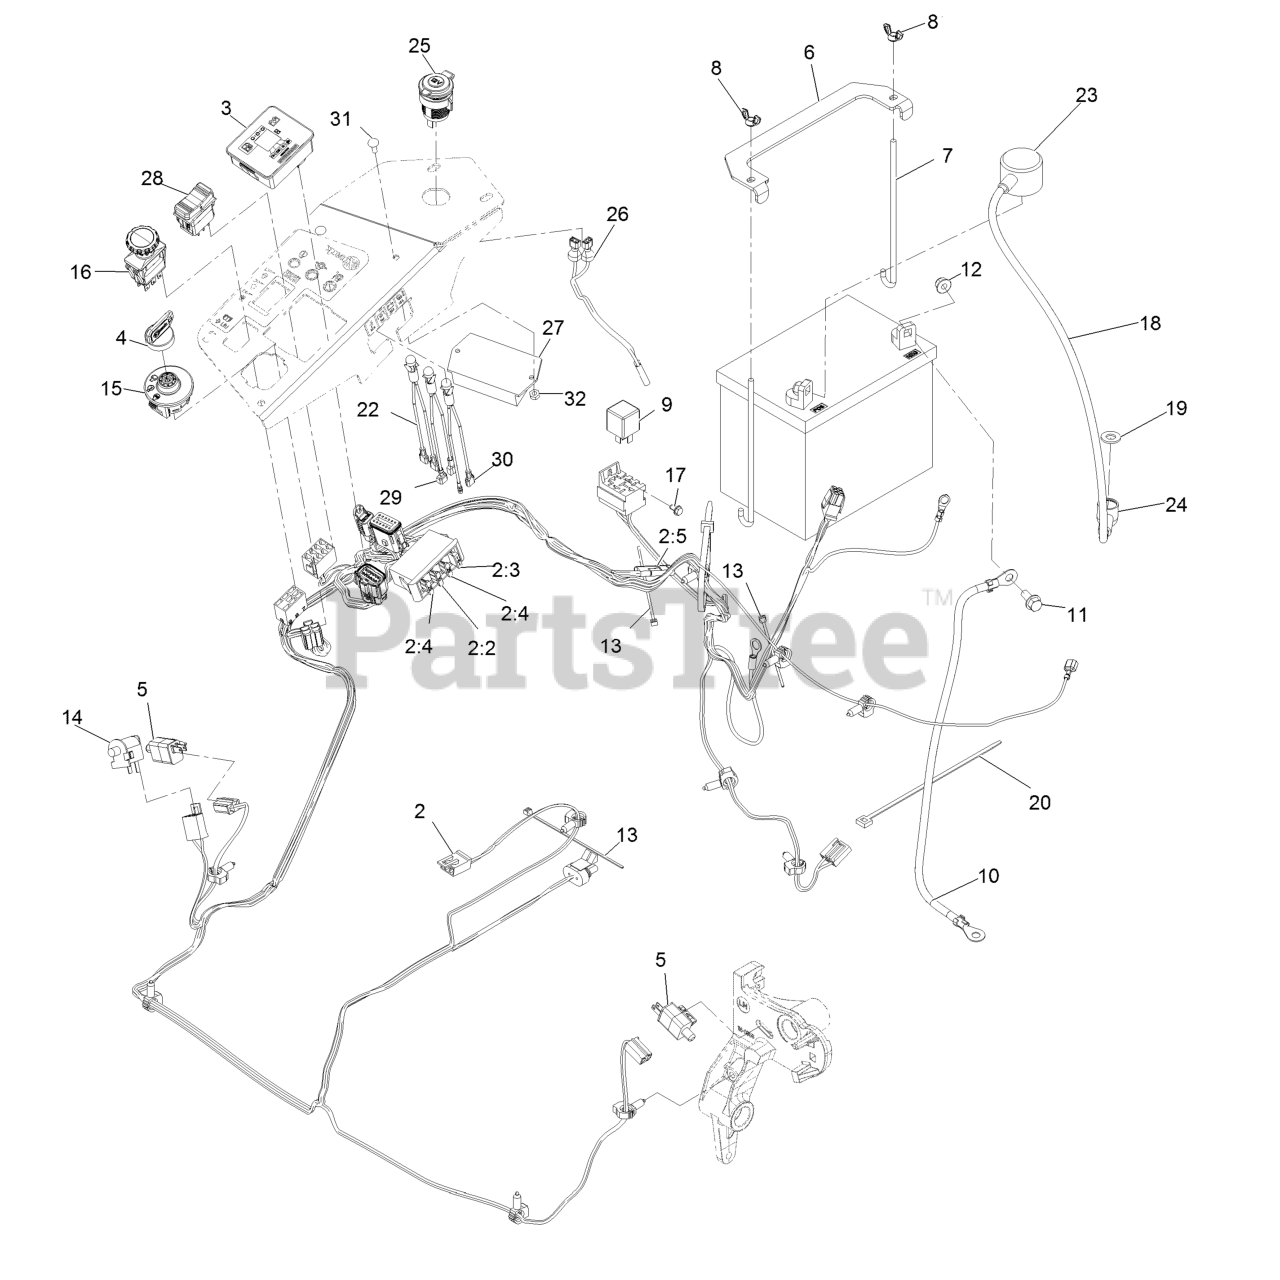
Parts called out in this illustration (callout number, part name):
2	HARNESS-WIRE
2:2	FUSE-BLADE, 10 AMP
2:3	FUSE-BLADE, 15 AMP
2:4	FUSE-BLADE, 25 AMP
2:5	CAP-PLUG
3	FUEL/HOUR METER ASM
4	KEYS-IGNITION (SPARE PAIR
4	KEY-IGNITION
6	STRAP-TIE DOWN, BATTERY
7	BOLT-HOLDDOWN
8	WINGNUT
10	CABLE-BATTERY, NEGATIVE
11	SCREW-HHF
12	NUT-HF, NI
13	TIE-CABLE
14	SWITCH-BAIL
16	SWITCH-PTO, 10 AMP
17	SCREW-HWH
18	CABLE-BATTERY, POSITIVE
19	WASHER-FLAT
20	TIE-PLASTIC
22	INDICATOR-LED, RED
23	INSULATOR-BATTERY
24	INSULATOR-SOLENOID
25	RECEPTACLE-12V
26	HARNESS, RECEPTACLE 12V
27	CONTROLLER-RED
28	SWITCH-ROCKER
29	LIGHT-LED, RED
30	LIGHT-LED, RED
31	SCREW-CARR
32	NUT-LOCK, NI
